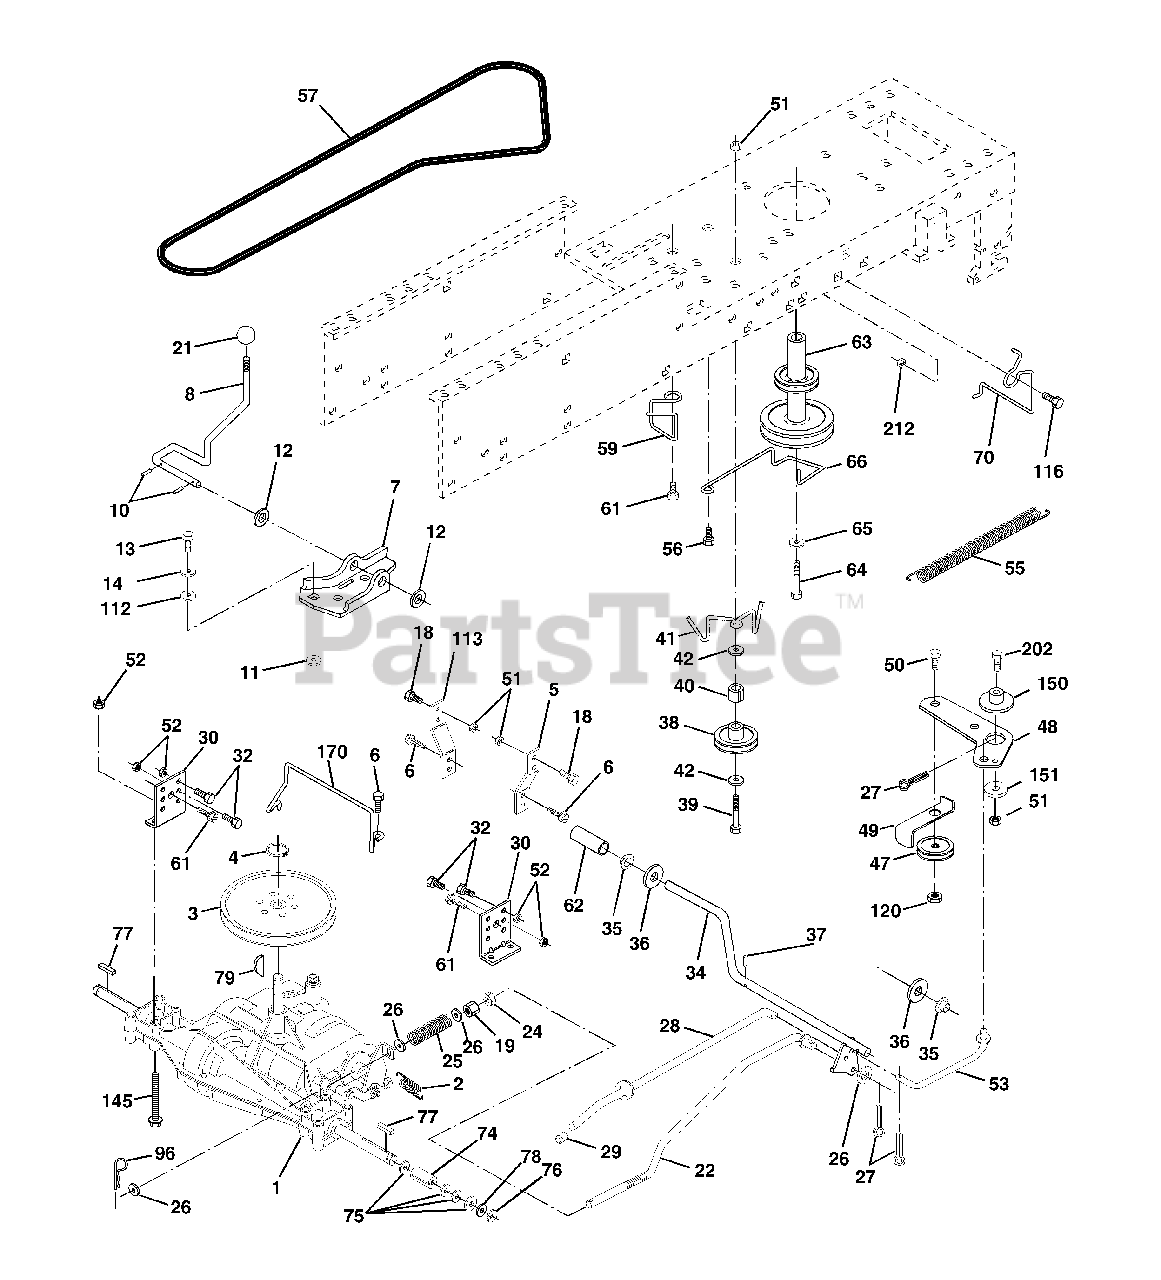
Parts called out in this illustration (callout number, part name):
2	Spring Extension Brake
3	Pulley Transaxle 18" tires
4	Ring Retainer # 5100-62
5	Strap Torque Rh Pnt Blk
6	Screw 5/16-18 X 3/4
7	Bracket T/A Saddle Shift
8	Rod Shifter Black(dana)
10	Pin,Cotter
11	Washer Plate Shf 388 Sq Hole
12	Washer 15/32 X 3/4 X 16ga
13	Bolt 1/4-28 UNF Gr. 8 W/Patch
14	Washer
18	Bolt Fin Hex 3/8-16 UNC x 1 Gr. 5
19	Nut
21	Knob Rd 1/2-13 Plstc Thds Blk
22	Rod Brake Lt
24	Nut
25	Spring Rod Brake 2 00 Zinc
26	Washer
27	Pin
28	Rod Brake Parking
29	Cap Parking Brake
30	Bracket Transmission
32	Bolt
34	Shaft Asm Pedal Foot
35	Bearing Nylon Blk 629 Id
36	Washer
37	Roll Pin
38	Pulley Idler Flat
39	Bolt Fin Hex 3/8-16 Unc x 3
40	Spacer Split
41	Keeper Belt Idler
42	Washer 13/32 X 13/16 X 12 Ga
47	Pulley Idler V Groove Plastic
48	Bellcrank Clutch
49	Retainer Belt Style Spring
50	Bolt
51	Nut
52	Nut
53	Link Clutch 7 66
55	Spring Return Clutch 6 75
56	Screw 3/8-16 x 1.0
57	V-belt Ground Drive 95
59	Keeper Belt Chassis Span Ctr.
61	Screw 3/8-16x3/4
62	Cover Pedal Blk Round
63	Pulley Engine
64	Bolt, Hex 7/16-20 x 4 Grade 5
65	Washer, Lock, Hvy Hlcl Spring 7/16
66	Keeper Belt Engine Flproof
70	Guide Belt Dr Mower Rh
74	Spacer Axle
75	Washer 25/32 X 1 1/4 X 16 Ga
76	E Ring
77	Key Square 2 0 X 1845/ 1865
78	Washer 25/32 X 1 5/8 X 16ga
79	Key Woodruff
96	Retainer Spring 1"
112	Washer 9/32 X 3/4 X 10 Ga
113	Strap Torque Lh
116	Bolt, Rdhd Sqnk 3/8-16 x 1.00
120	Nut Lock Flg 3/8-16
145	Bolt Hex Flghd 5/16-18 x Gr. 5
150	Spacer Retainer
151	Washer 13/32 x 2 x 10 Ga.
170	Keeper Belt
202	Bolt Carr. Sh. 3/8-16 x 1-3/4 Gr. 5
212	Nut Hex Flange Lock
